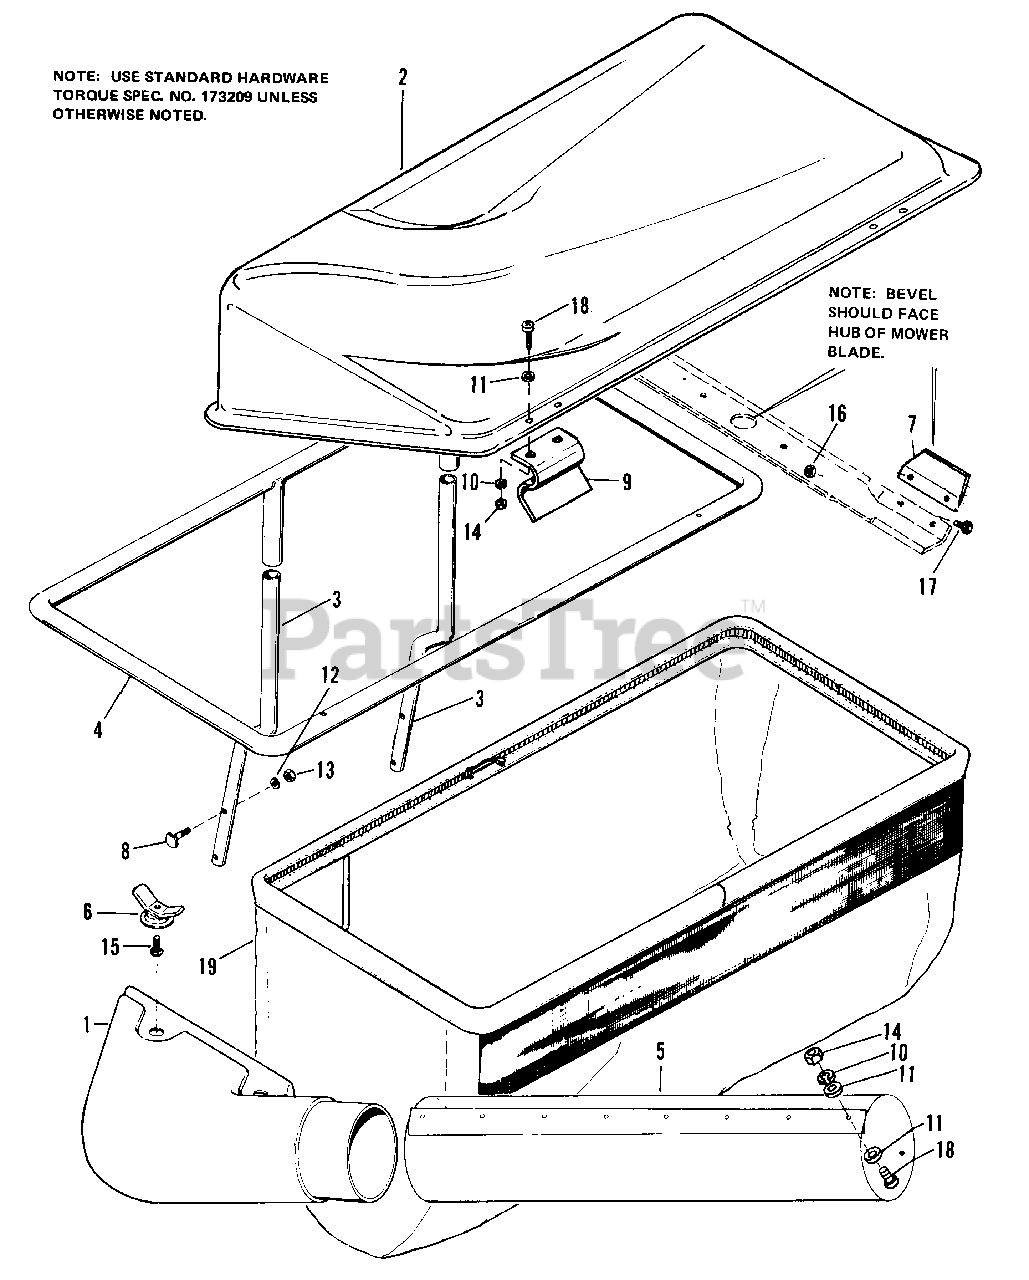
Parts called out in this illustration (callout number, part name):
3	SUPPORT, Verticle
4	SUPPORT ASSY
5	TUBE, Intake
7	PLATE, Lift
8	BOLT, Curved Head
10	LOCKWASHER, No. 10, 3/16, Internal Tooth
11	WASHER, Plain, 3/16
12	LOCKWASHER. Spring, 5/16
13	NUT, Hex, 5/16-18
14	NUT, Hex, Mach. No. 10-32
15	BOLT, Carriage, 5/16-18 x 1
16	NUT, Hex, Lock, 5/16-18
17	CAPSCREW, Hex Hd., 5/16-18 x 5/8
18	SCREW, Truss Hd., No. 10-32 x 1/2
19	GRASS BAG
